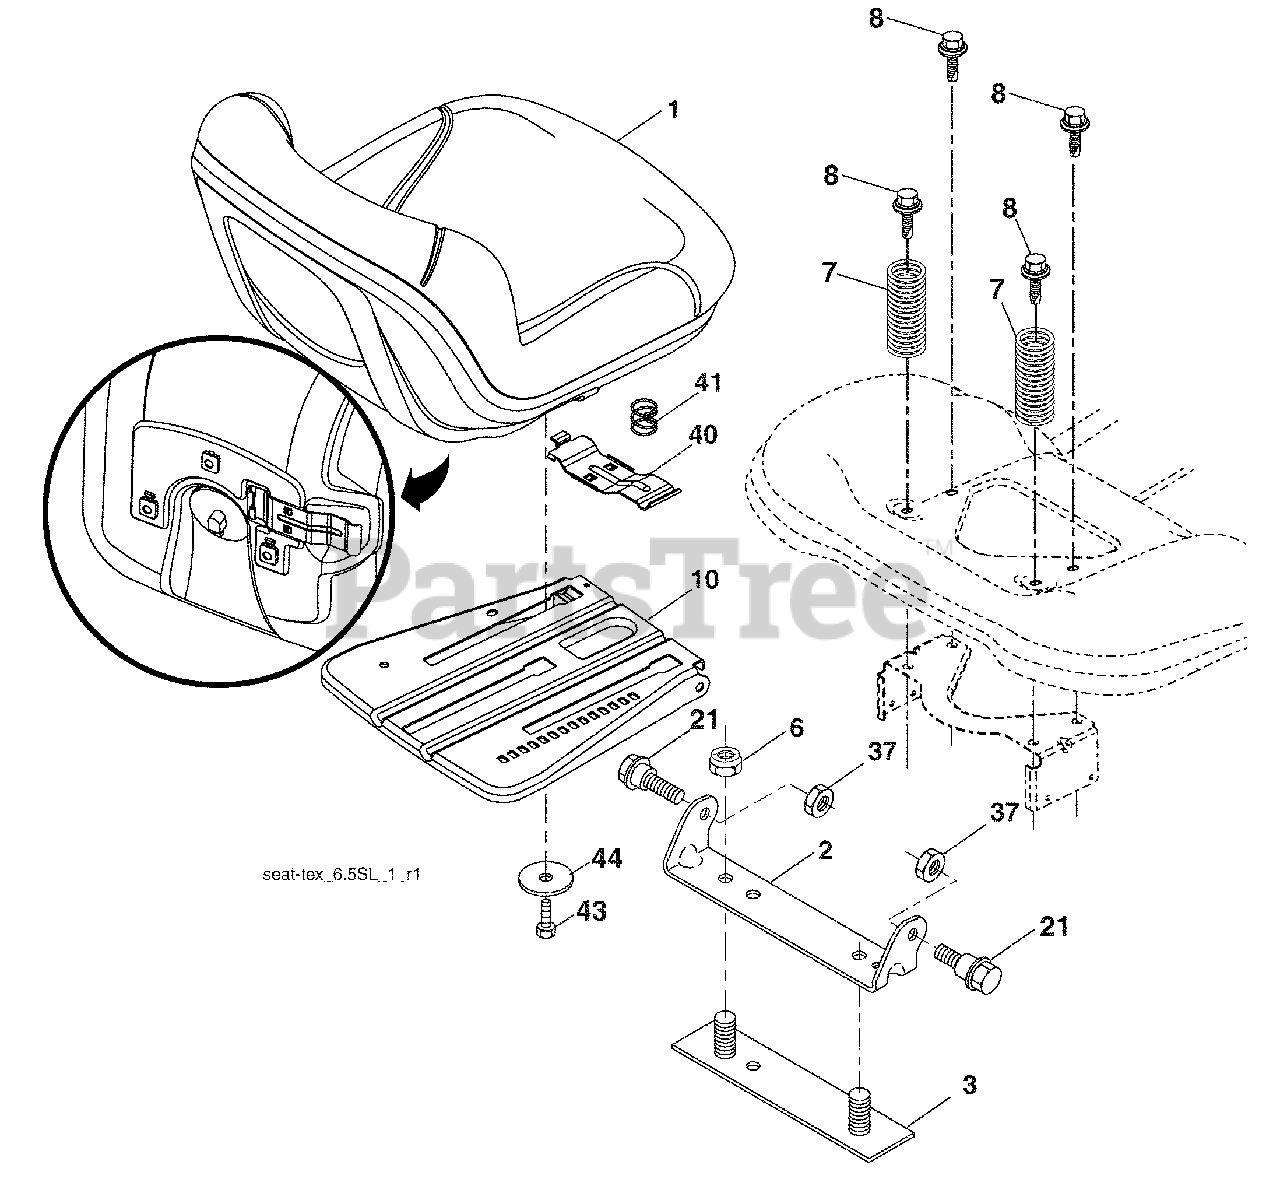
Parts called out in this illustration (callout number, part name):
1	Seat
2	Bracket Pivot Fender
3	Strap, Asm Fender
6	Nut, Lock w/Ins. 3/8-16 unc
7	Spring, Seat Cprsn
8	Bolt 5/16-18 unc x 3/4 w/Sems
10	Pan, Seat
21	Bolt, Shoulder 5/16-18
37	Nut, Lock 5/16-18 unc
40	Handle Slide Seat
41	Spring Latch Seat
43	Bolt Fin Hex 3/8-16 unc x 3/4
44	Washer 13/32 x 2-3/8 x 12 Ga.
